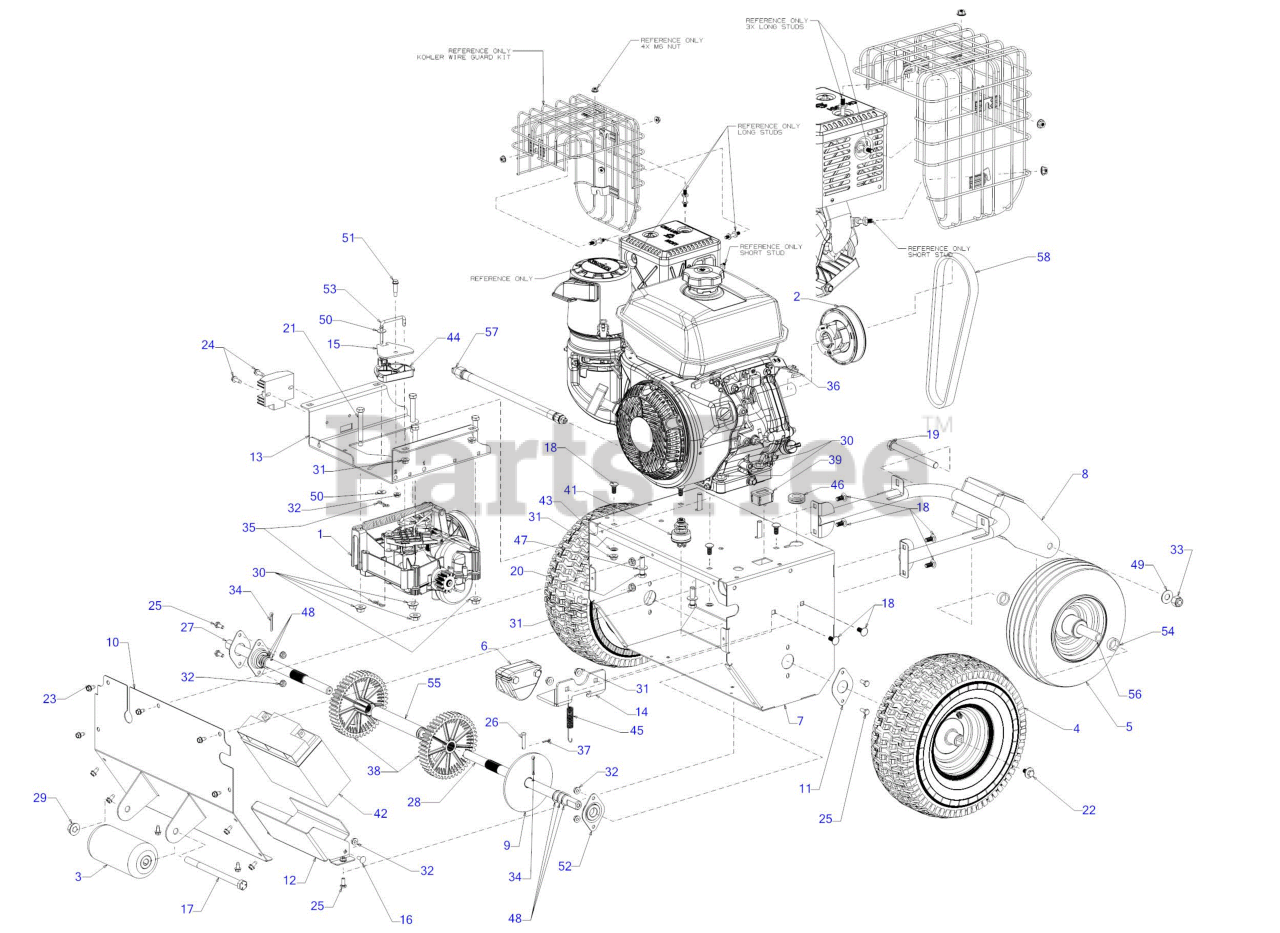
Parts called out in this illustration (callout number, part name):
1	TRANSMISSION ASSEMBLY BLOWER
2	PULLEY ASSEMBLY
3	ROLLER ASSEMBLY
4	WHEEL ASSEMBLY COMPLETE
5	WHEEL ASSEMBLY 11 x 4 x 5
6	TRANSFER CASE BRAKE ASSEMBLY
9	ROTOR HUB ASSEMBLY
15	CABLE GUIDE COVER PLATE
16	CARRIAGE BOLT 1/4-20 x .62
17	SCREW 1/2-13 x 7 GR5
18	CARRIAGE BOLT 5/16-18 x .75
19	SCREW 1/2-20 x 5.50 GR5
20	SCREW 3/8-16 x 1.50
21	SCREW 3/8-16 x 3 GR8
22	SCREW 5/16-24 x .750 GR5
23	SCREW 1/4-20 X.500
24	SCREW 1/4-20 x .750
25	SCREW 1/4-20 x .620 GR5
26	CLEVIS PIN
27	13.10" AXLE (LH)
28	14.50" AXLE (RH)
30	FLANGE LOCK NUT
31	FLANGE NUT
32	LOCK NUT 1/4
33	HEX NUT CENTER
34	COTTER PIN-5/32 DIA
35	BOW TIE COTTER PIN 1/4-5/16
36	HEX KEY 1/4 X 3/16 X 0.75
37	COTTER PIN-3/32X62
38	NYLON GEAR 45 TOOTH
41	KEY SWITCH (3 POSITION) (Add 925-06908)
42	SEALED BATTERY 12 VOLT
44	CABLE GUIDE
45	EXTENSION SPRING
46	RUBBER GROMMET
47	FLAT WASHER
48	FLAT WASHER .750X1.000X.060:HD
49	FLAT WASHER
50	FLAT WASHER
51	SHOULDER SCREW
52	BALL BEARING
53	SPEED CONTROL ROD LINK
54	SPACER .790 ID 1
55	AXLE SUPORT TUBE
56	WHEEL SPACER
57	OIL DRAIN HOSE
